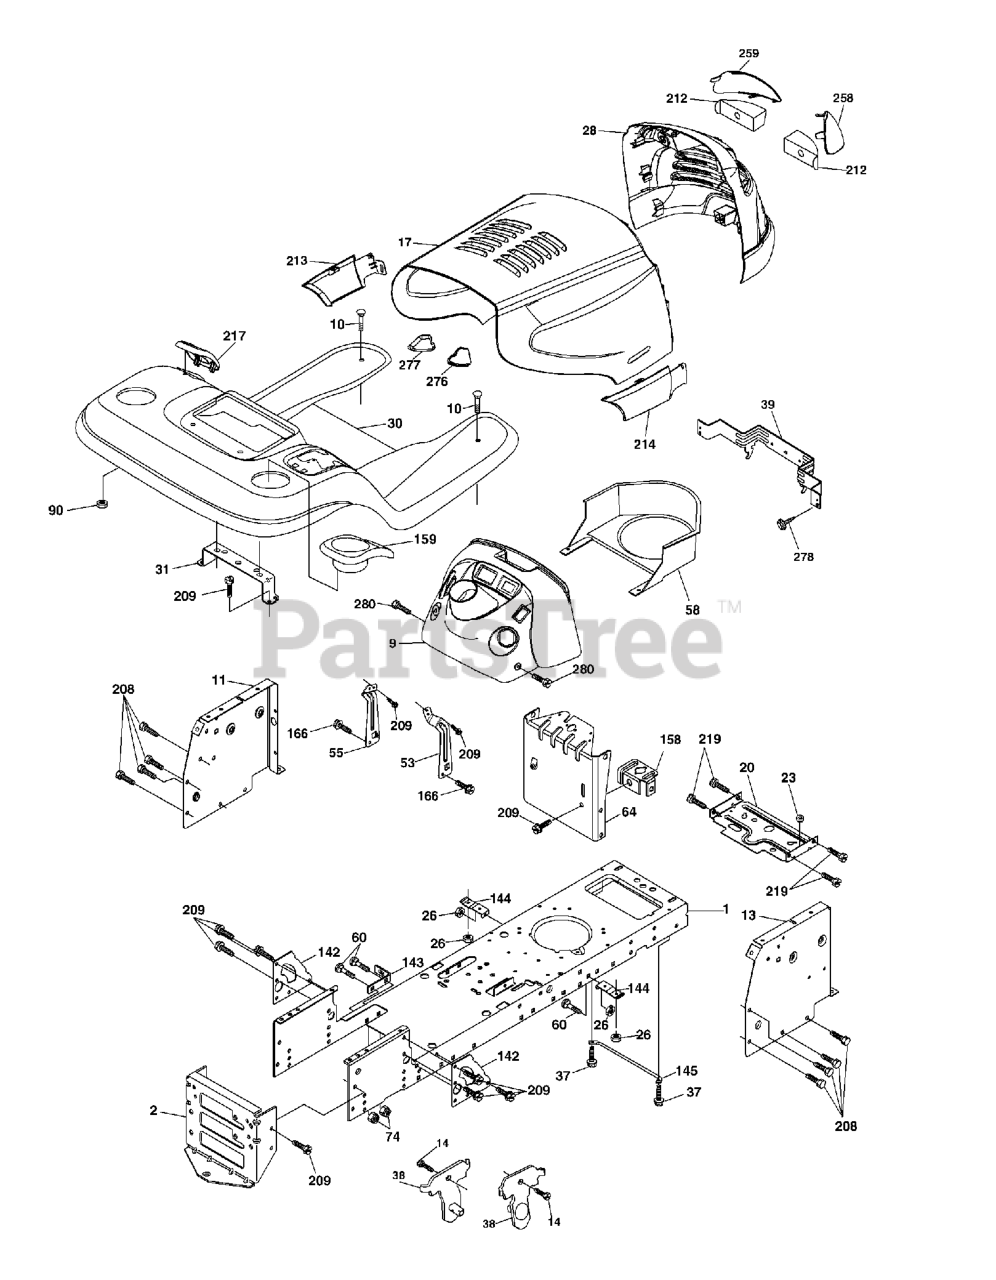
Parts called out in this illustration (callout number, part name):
1	CHASSIS STAMPING
2	DRAWBAR, 12GA
9	DASH.NON-TEX.GRAY
10	BOLT D
11	PANEL.DASH.LH.LTX
13	PANEL DASH RH
14	SCREW LT
17	HOOD
20	PLATE MTG.BATTERY/FUEL TANK
23	BUSHING.SNAP.NYL.BLK.
26	NUT
28	GRILL/LENS ASSY ( YT MODEL)
30	FENDER
31	BRACKET.SUPPORT.FENDER
37	Screw 5/16-18 x 1/2 Hex, Self Tapping 5/16-18 x 1/2
38	BRACKET.ASM.PIVOT.MOWER.REAR
39	BRACKET PIVOT LASER
53	BRACKET DASH RH
55	BRACKET DASH LH
58	AIR DUCT ENGINE
60	Bolt - Rd. Hd. Sq. Neckiage 3/8 16 x 3/4
64	DASH LOWER
74	LOCKNUT
90	NUT.PUSH.3/16
142	PLATE REINFORCEMENT
143	BRACKET, SWAYBAR CHASSIS
144	BRKT, FOOT REST
145	ROD PIVOT CHASSIS/HOOD
158	BRACKET PARKING BRAKE
159	GREY CUP HOLDER
166	SCREW
208	SCREW 3/8-16X1/2
209	SCREW, 3/8-16X3/4
212	INSERT LENS
213	SKIRT SIDE LH
214	SKIRT SIDE RH
217	CONSOLE FUEL WINDOW
219	SCREW
258	LENS ELITE CLEAR RH
259	LENS ELITE CLEAR LH
276	BUMPER HOOD RH
277	BUMPER HOOD LH
278	SCREW
280	SCREW THDROL 3/8-16 X 1-1/2
